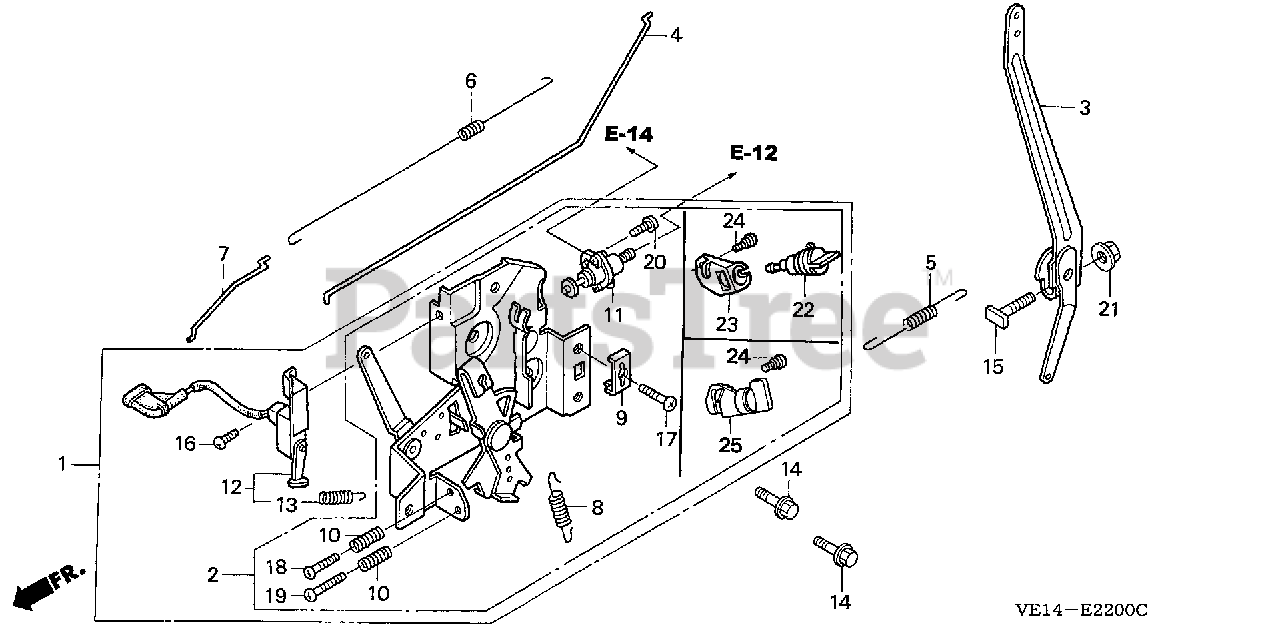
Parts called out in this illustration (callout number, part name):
1	CONTROL ASSY.
3	ARM, GOVERNOR
4	ROD, GOVERNOR
5	SPRING, GOVERNOR
6	SPRING, THROTTLE RETURN
7	ROD, CHOKE
8	SPRING, LEVER
9	HOLDER, CABLE
10	SPRING, CONTROL ADJUSTING
11	PETCOCK ASSY.
12	SWITCH ASSY., ENGINE STOP
13	SPRING, SWITCH CONTROL
14	BOLT, FLANGE (6X14) (CT200)
15	BOLT, GOVERNOR ARM
16	SCREW, PAN (4X8)
17	SCREW, PAN (5X16)
18	SCREW, PAN (5X20)
19	SCREW, PAN (5X25)
20	SCREW-WASHER (5X12)
21	NUT, FLANGE (6MM)
22	PETCOCK ASSY.
23	BRACKET, PETCOCK
24	SCREW, SHOULDER (5X12)
